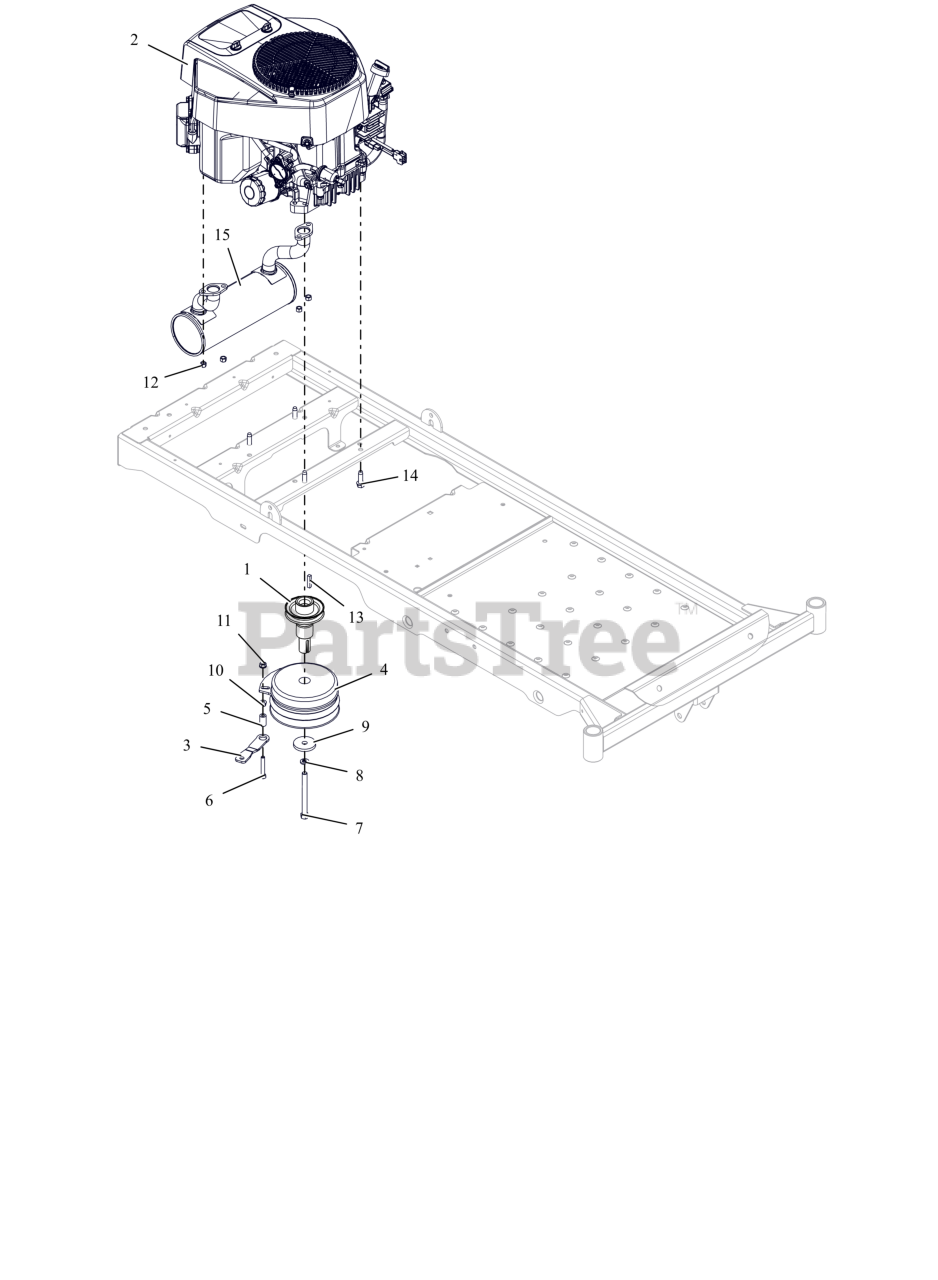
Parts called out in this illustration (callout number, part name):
1	WLDMT, CRANK SHAFT ADAPTER- BRIGGS
2	ENGINE, ARIENS 635cc
3	BRKT, CLUTCH
4	CLUTCH, 105 FT*LB MONO POLE
5	SPACER, RUBBER 5/16 IDX1.0 LG
6	BLT, HEX .31-18X2.00 G5 ZCC
7	BLT, HEX .44-20X4.50 G8 ZCC NT
8	WSHR, LK-REG .438X.109 ZCC
9	WSHR, FLT .469X2.00X.250 ZCC
10	NUT,SPNLK-FLG .31-18 G5 ZCC
11	NUT,LK-CTR-FLG .31-18 GF ZCC
12	NUT-LK-TOP-FLG M8 ZCC
13	KEY-SQ .25 X 1.25 X .25 SAE
14	SCR,TAP .375-16X1.25HWH TR ZCC
15	WLDMT, LONCIN MUFFLER 635CC
